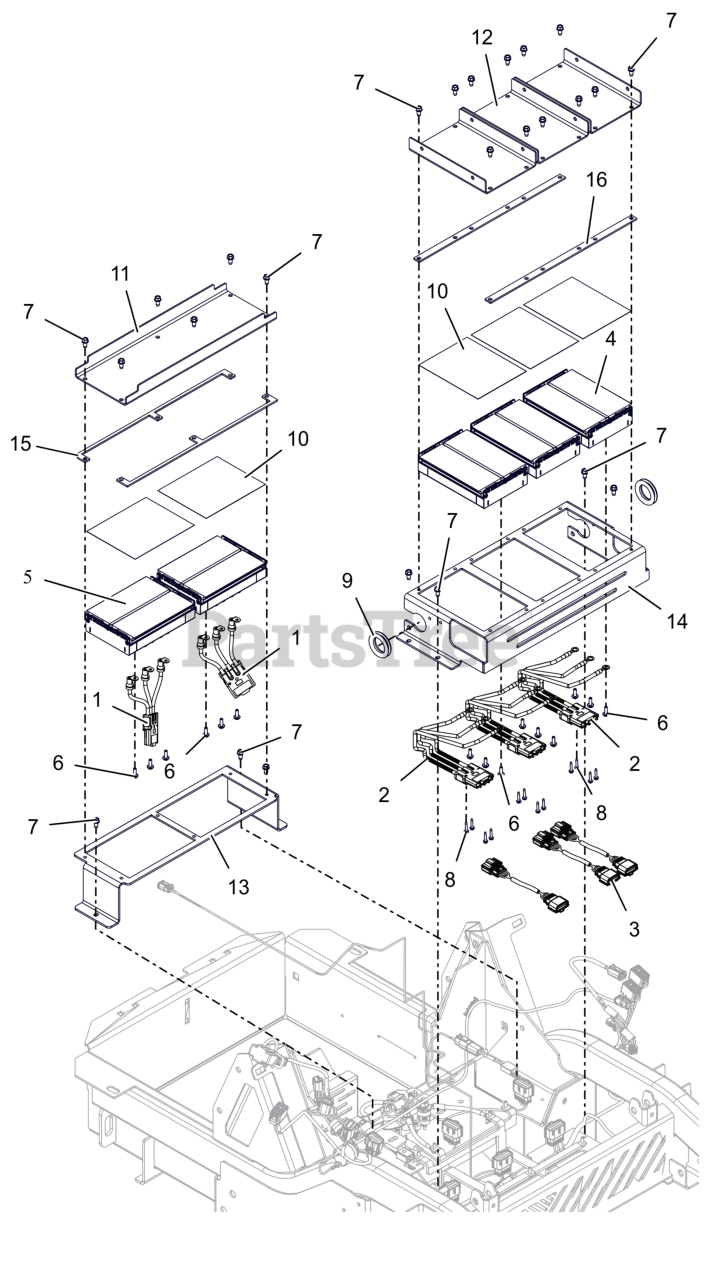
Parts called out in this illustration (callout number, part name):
1	HARNESS, DRIVE CONTROLLER
2	HARNESS, DECK CONTROLLER
3	HARNESS, DECK CNTRL JUMPER
4	KIT, MY23 52 DECK CONTROLLER
5	KIT,MY23 PTEV DRVIE CONTROLLER
6	BLT,HEX M5-.8X16 EP30 G8.8 ZCC
7	SCR-TAP .25-20X.50 HWH ZCC
8	SCR-TAP #6-32X.75 HWH ZCC
9	GROMMET 1.25ID X 1.5OD
10	PAD, THERMAL
11	PLATE, HEAT SINK-REAR
12	PLATE, HEAT SINK-FRONT
13	MOUNT, CNTRL -DRIVE (BLACK)
14	MOUNT, CONTROLLER PLATE-FRONT (BLACK)
15	SPCR, HEAT SINK (BLACK)
16	SPCR, HEAT SINK - FRONT (BLACK)
